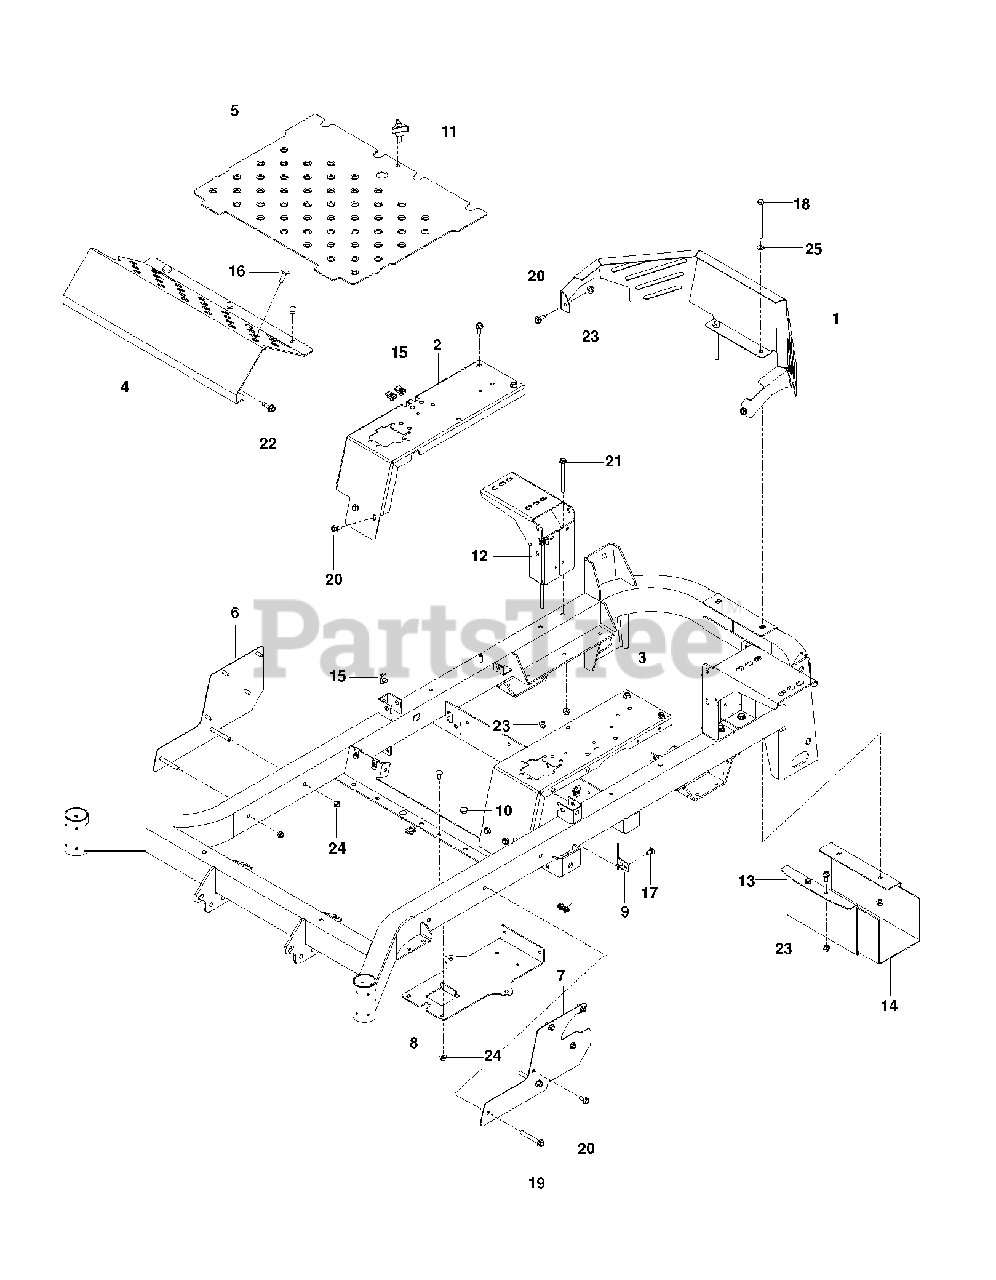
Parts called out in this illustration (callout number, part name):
1	GUARD, REAR ULTRA, BLUE
2	PANEL, FILLER RT, BLUE
3	PANEL, FILLER LT, BLUE
4	PLATE, FOOT REST - RAM DK BLUE
5	FLOOR PAN W/DECALS
6	SIDE, RT, BL
7	SIDE, LT, BL
8	PLATE, BATTERY, BLACK
10	GROMMET, BUMPER
11	KNOB W/STUD
12	MOUNT, TANK, ZT BLK
14	HEAT SHIELD
15	U-CLIP 5/16-18 NUT RETAINER
16	RHSNB 5/16C X 1
17	BOLT 5/16C X 3/4" CARRIAGE
18	HCS 5/16C X 4
19	HHFS 3/8-16 X 2 3/4
20	HHFS 5/16-18 X 3/4
21	HHFS 5/16-18 X 3 3/4
23	5/16-18 NYLOC FLANGE NUT
24	NUT HEX 3/8-16 NYLON, THIN
25	FLAT WASHER 5/16 SAE
